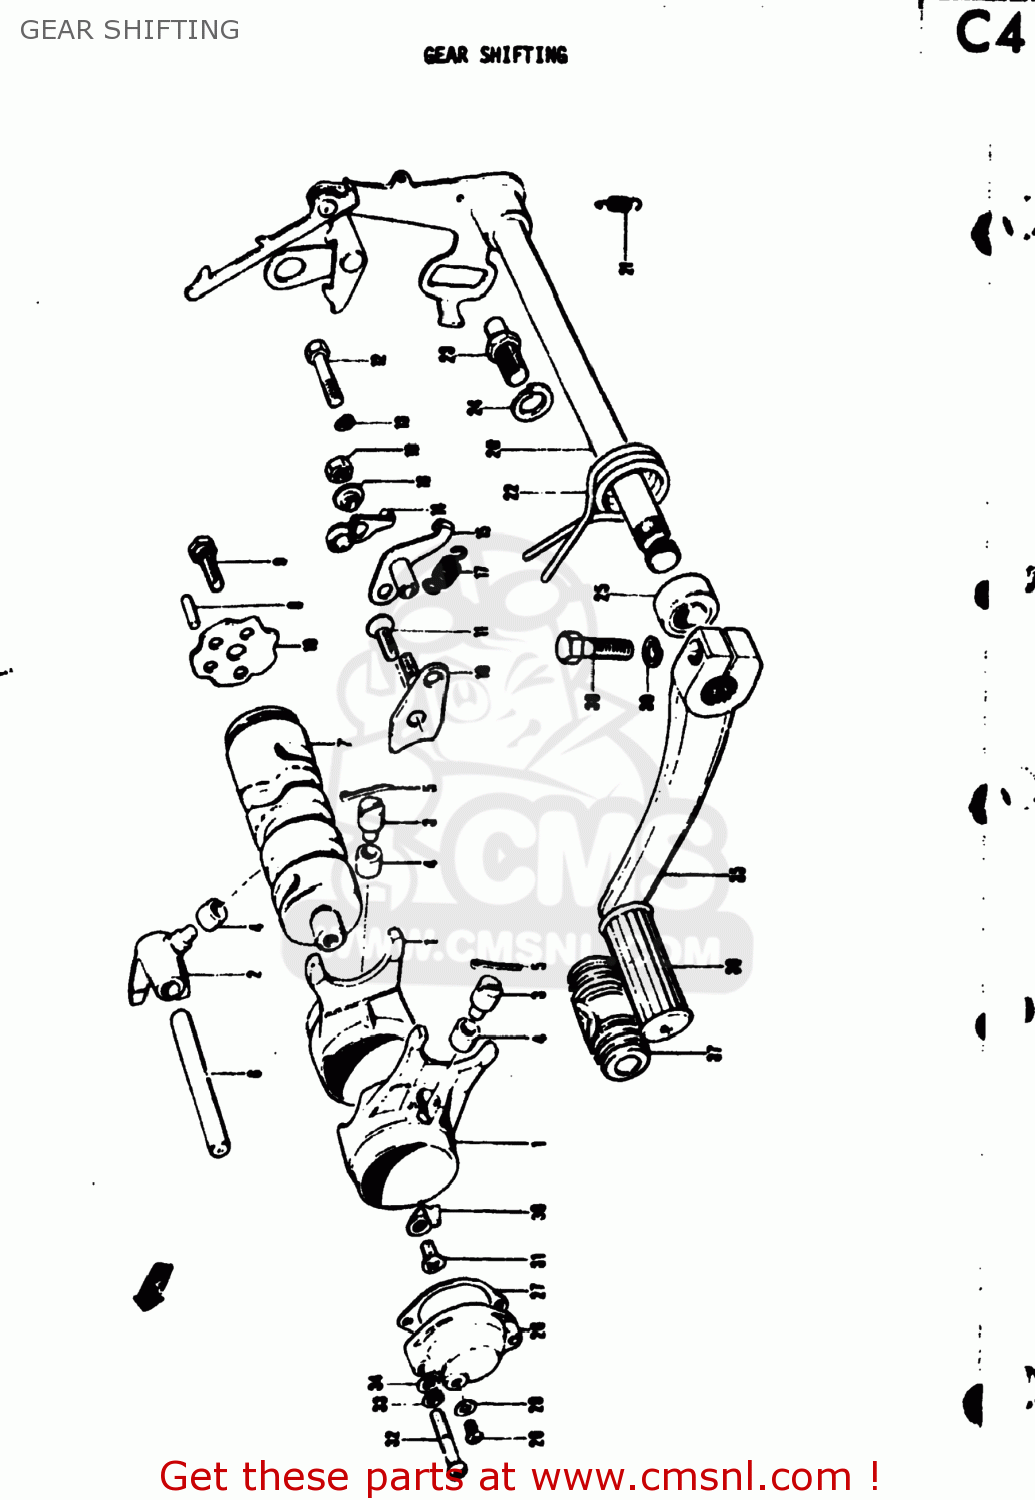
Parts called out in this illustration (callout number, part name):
1	FORK,GEAR SHIFT NO.1
2	FORK,GEAR SHIFT NO.2
3	PIN
4	SPACER
5	PIN 25X20
6	SHAFT,GEAR SHIFT FORK
7	CAM,GEAR SHIFT
8	ROLLER(4X13.8)
9	BOLT
10	GUIDE,GEAR SHIFTING CABLE
11	SCREW
12	BOLT
13	LOCK WASHER
14	STOPPER,GEAR SHIFTING
15	HOLDER,SHIFTING CAM STOPPER
16	SPACER (6X14X4)
17	SPRING
18	NUT
19	PLATE,GEAR SHIFT CAM
20	SHAFT,GEAR SHIFT
21	SPRING
22	SPRING
23	STOPPER,GEAR SHIFT ARM
24	LOCK WASHER
25	OIL SEAL
26	BODY,GEAR SHIFT SWITCH
27	28
28	SCREW
29	WASHER
30	POINT,NEUTRAL INDICATOR SWITCH CON
31	SCREW
32	SCREW
33	LOCK WASHER
34	WASHER
35	LEVER ASSEMBLY,GEAR SHIFTING
36	RUBBER,GEAR SHIFT PEDAL
37	RUBBER,GEAR SHIFT PEDAL
38	BOLT
39	LOCK WASHER
